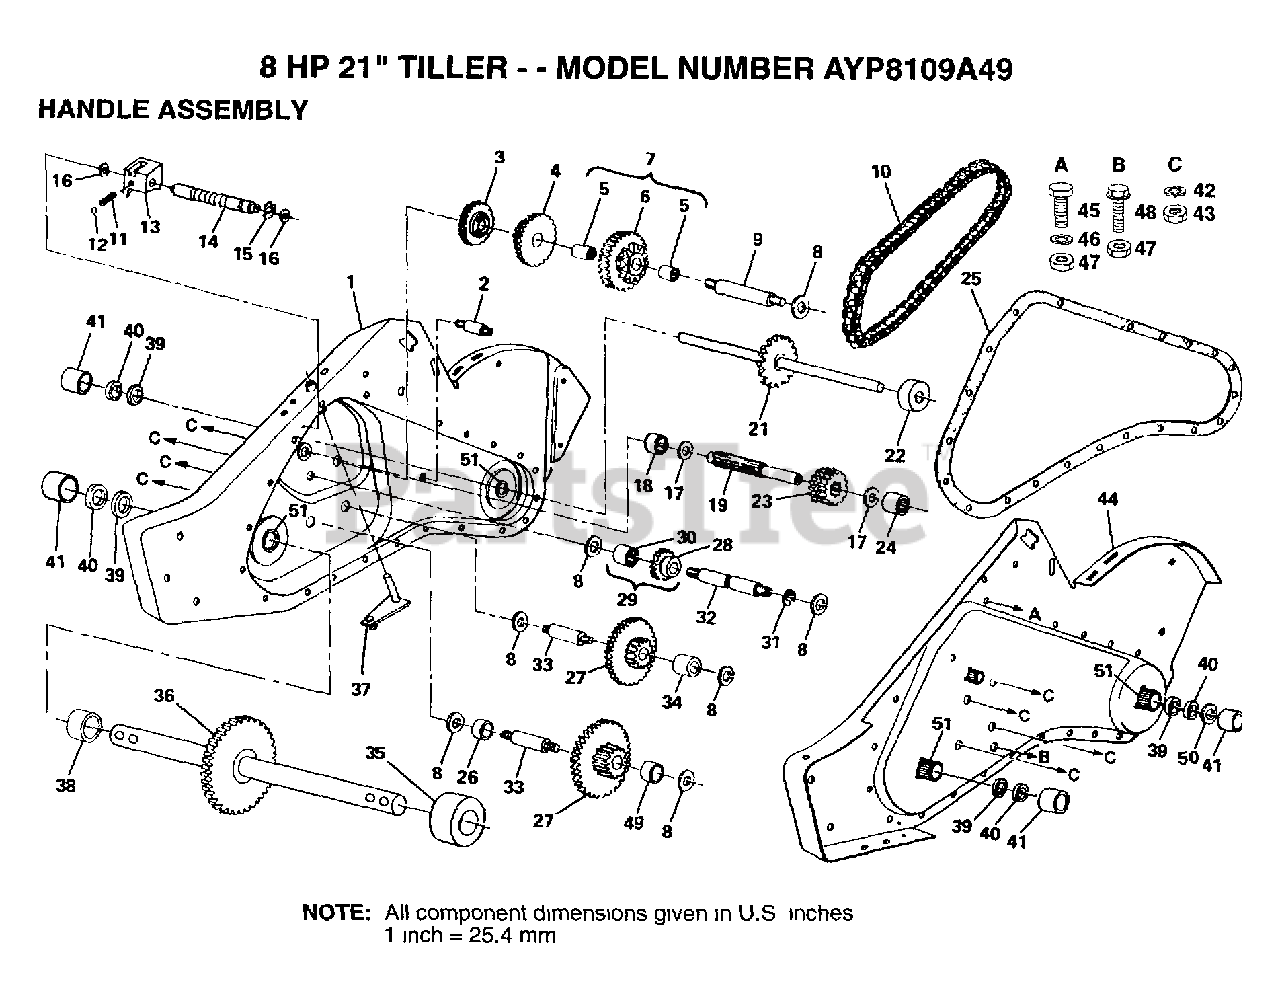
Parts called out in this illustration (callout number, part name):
2	BOLT TI
3	REVERSE GEAR TI
4	CLUSTER GEAR TI
5	"CRT, BEARING"
7	SPROCKET ASSY TI
8	WASHER
9	REDUCTION SHFT TI
10	CHAIN TI
11	SPRING-SHIFT CRT
13	SHIFT FORK TI
14	SHIFT SHAFT TI
15	KLIP RING
17	"T, BEARING"
18	"TI, BEARING"
19	SHAFT INPUT T
21	SHAFT TINE CRT
23	INPUT PINION TI
24	NEEDLE BRNG LT
25	GEARCASE GSKT TI
26	SPACER CRT
27	GEAR CLUSTER CRT
28	REVERSE GEAR TI
29	GEAR ASSY TI
30	NEEDLE BEARING TI
31	KLIP RING
32	REVERSE SHAFT TI
33	SHAFT CRT
34	SPACER CRT
35	SPACER CRT
36	SHAFT ASSY CRT
38	SPACER CRT
39	OIL SEAL STD
40	SEAL, RING RUBBER
41	CUP.FORMED.
42	LOCKWASHER
43	NUT.ASF.HEX.7/16
45	BOLT
46	LOCKWASHER
47	NUT.HEX.5/16-18
48	BOLT TI
49	SPACER CRT
50	RING SPIRAL CRT
